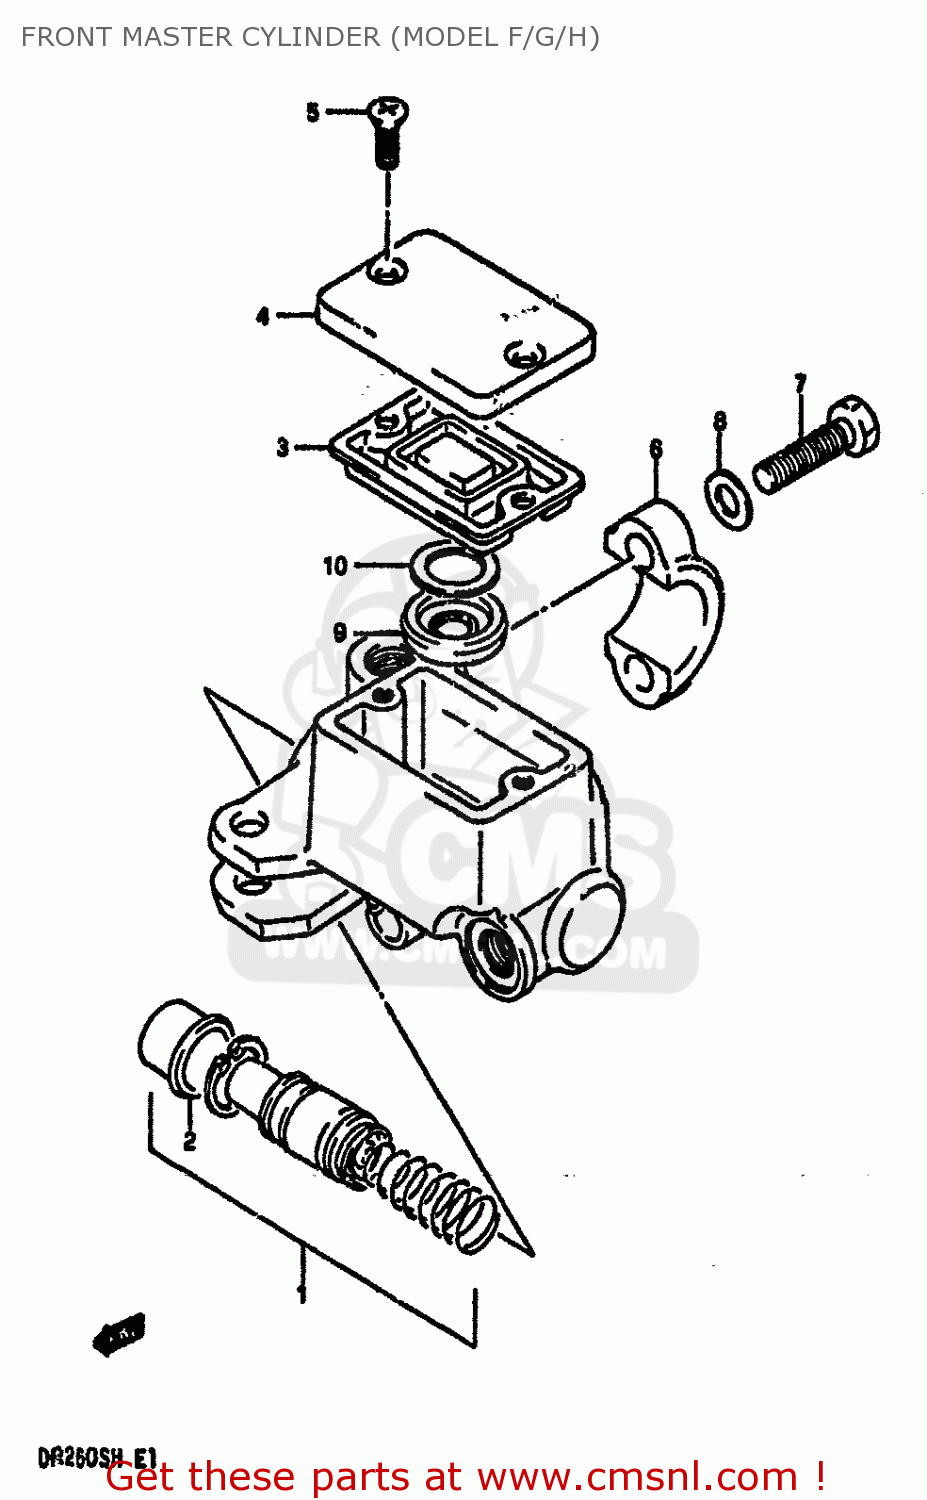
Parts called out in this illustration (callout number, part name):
1	PISTON/CUP SET
2	BOOT
3	DIAPHRAGM
4	CAP
5	SCREW
6	HOLDER
7	BOLT
8	WASHER
9	SEPERATOR
10	PLATE
